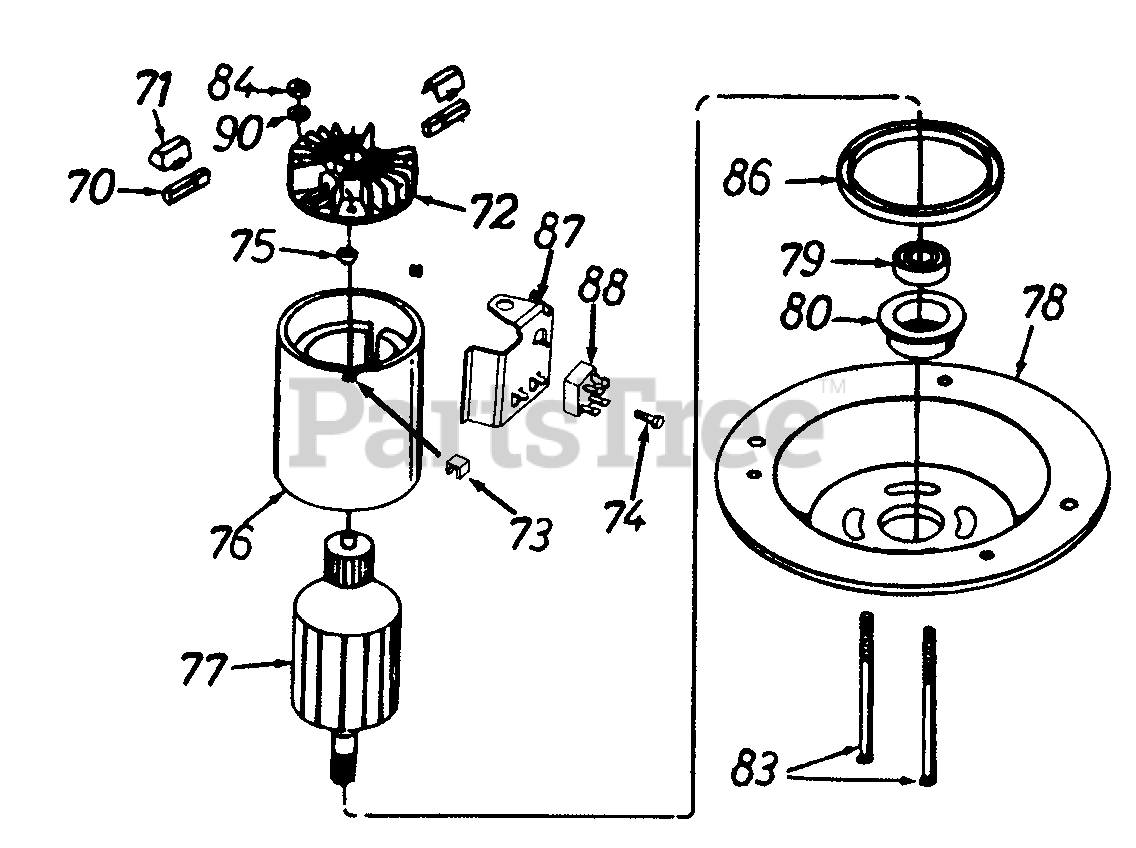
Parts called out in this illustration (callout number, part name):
70	Brush and Liner Ass'y.
71	Brush Holder Cap
72	End Shield Ass'y. w/Plug
73	Insulator Wire (Output)
74	Hex Tap Scr. #10-16 x .62" Lg.
75	Needle Bearing
77	Armature Ass'y.
78	Motor End Plate
79	Ball Bearing
80	Bearing Adapter
83	Carriage Bolt
84	Hex L-Nut 1/4-20 Thd.
86	Motor Hsg. Insulator
87	Brkt.-Rectifier/Heat Sink
88	Rectifier
90	FI-Wash..26" I.D. x.72" O.D.
